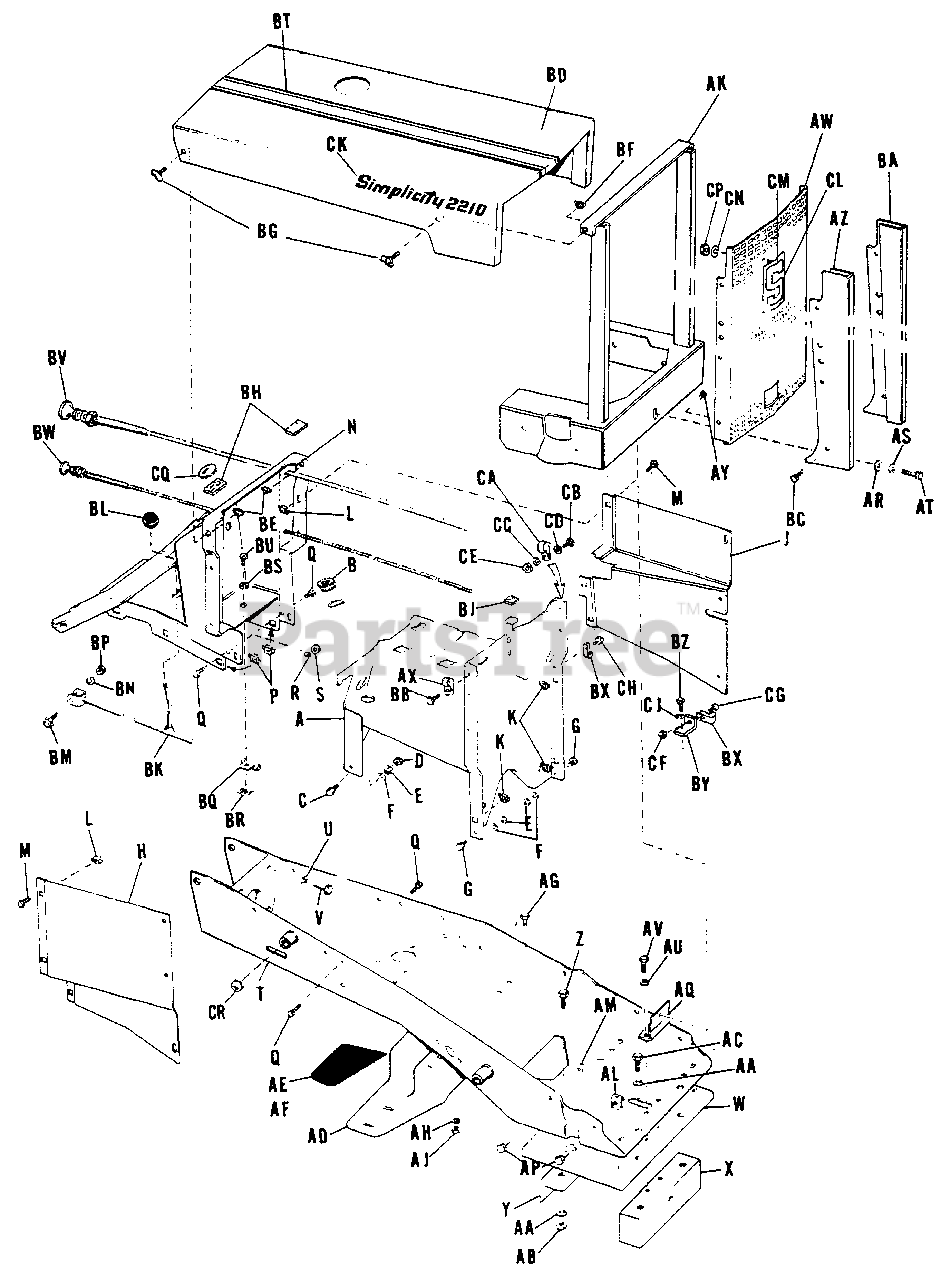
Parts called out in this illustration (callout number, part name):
A	Support Assembly, Fuel Tank & Battery
B	Steering Bushing
C	Hex. Cap Screw, 5/16"-18 x 1-1/4"
D	Full Lock Hex. Nut, 5/16"-18
E	Full Hex. Nut 5/16"-18
F	Lock Washer, 5/16"
G	Hex. Cap Screw, 5/16"-18 x 5/8"
H	R.H. Side Panel
J	L.H. Side Panel
K	Nut Retainer
L	Nut Retainer
M	Hex. Cap Screw, 1/4"-20 x 5/8"
N	Inst. Panel Assembly
P	Nut Retainer (Frame Cover)
Q	Hex. Cap Screw, 1/4"-20 x 5/8"
R	Lock Washer, 1/4"
S	Full Hex. Nut, 1/4"-20
T	Frame Assembly
U	Lock Washer, 7/16"
V	Hex. Cap Screw, 7/16"-14 x 1-1/2"
W	Base Weight
X	Front Support, 1-3/4" x 2-1/2" x 8-5/8"
Y	Angle Assembly (Frame Rear)
Z	Hex. Cap Screw, 7/16"-14 x 1-1/2"
AA	Lock Washer, 7/16"
AB	Full Hex. Nut, 7/16"-14
AC	Hex. Cap Screw, 7/16"-20 x 1-1/2"
AD	Foot Rest
AE	L.H. Foot Rest Pad
AF	R.H. Foot Rest Pad
AG	Hex. Cap Screw, 3/8"-16 x 3/4"
AH	Lock Washer, 3/8"
AJ	Full Hex. Nut, 3/8"-16
AK	Cover & Tube Assembly
AL	Retainer Nut (Front)
AM	Retainer Nut, (Rear)
AP	Nut-hex-Whiz-Lock Flange. 5/16-18 x 3/4"
AQ	Bracket Assembly
AR	Plain Washer, 5/16"
AS	Lock Washer, 5/16"
AT	Hex. Cap Screw, 5/16"-18 x 1-1/4"
AU	Lock Washer, 5/16"
AV	Hex. Cap Screw. 5/16"-18 x 1-1/2"
AY	Self Tapping Screw, #810 x 1/2"
AZ	R.H. Side Plate
BA	L.H. Side Plate
BC	Self Tapping Screw, #10 x 1/2"
BB	Nut Retainer (Rear)
BF	Nut Retainer (Front)
BG	Thumb Screw
BK	Shifter Rod Assembly
BM	Hex Cap Screw, 5/16"-18 x 1-1/2"
BN	Lock Washer, 5/16"
BP	Full Hex. Nut, 5/16"-18
BQ	Shift Rod Guide Assembly
BR	Retainer Nut
BS	Lock Washer, 1/4"
BT	Hood Strip
BU	Hex. Cap Screw, 1/4"-20 x 5/8"
BV	Throttle Control
BW	Choke Control
BX	Bowden Wire Clip
BY	Throttle Cable Bracket
BZ	Self Tapping Screw, 1/4"-20 x 5/8"
CB	Hex, Cap Screw, 1/4"-20 x 5/8"
CC	Lock Washer, 1/4"
CD	Plain Washer, 1/4"
CE	Full Hex. Nut, 1/4"-20
CF	Full Hex. Nut, #10-32
CG	Mach. Rd. Hd. Screw, #10-32 x 3/8"
CH	Self Tapping Rd. Hd. Screw, #10-24 x 1/2"
CJ	Lock Washer
CK	Simplicity & No. 2210 Film
CL	Plate, Assy.,
CM	Emblem "S"
CN	Washer Lock
CP	Hex Nut #10-24
CQ	Plug Button
CR	Plug Button
